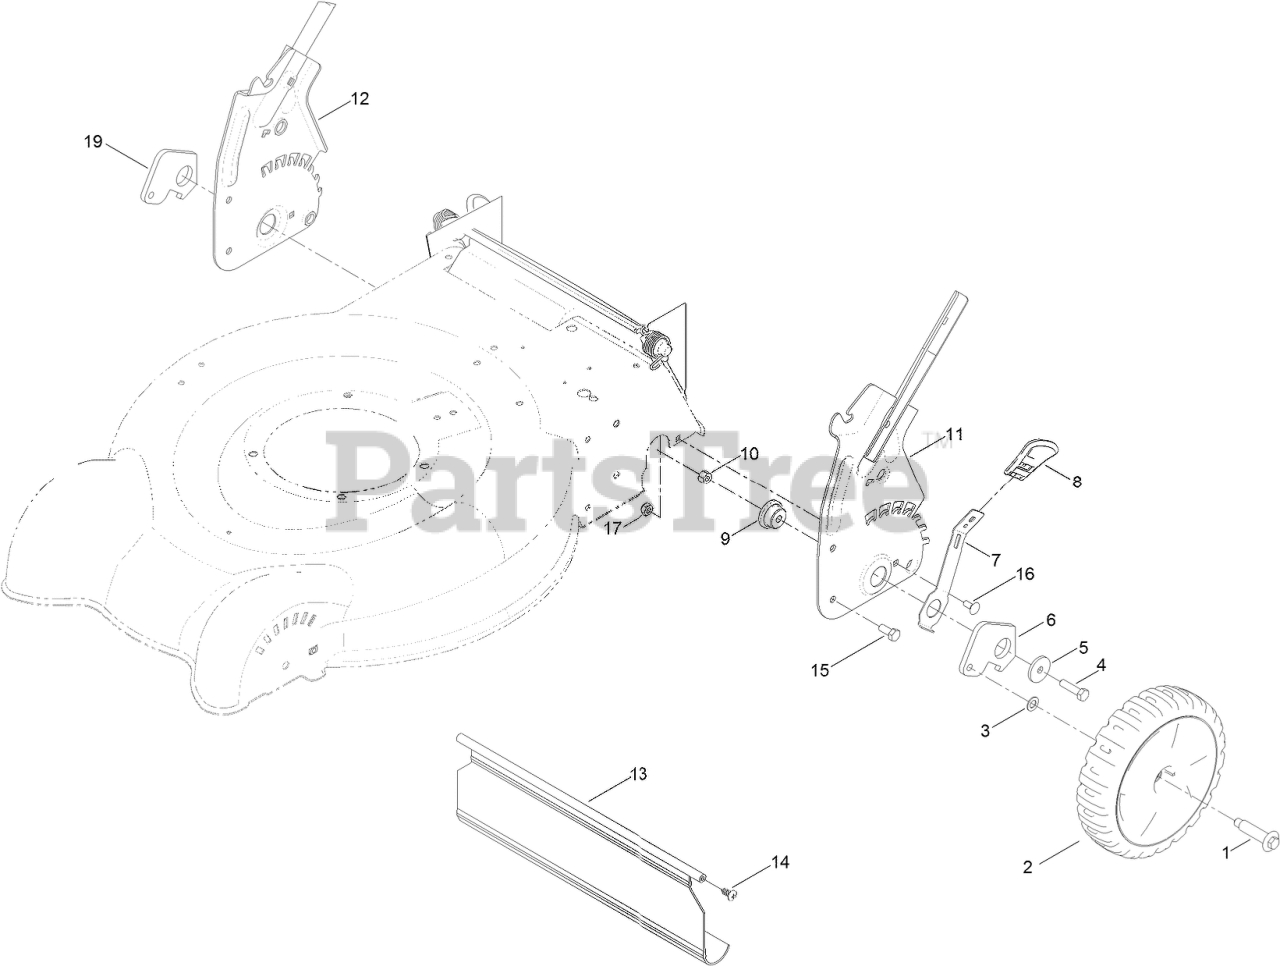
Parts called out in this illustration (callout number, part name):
1	BOLT-SHOULDER
2	8 INCH WHEEL AND TIRE ASM
3	WASHER
4	SCREW-HH
5	Washer-Flat
6	Arm-Pivot, Rear (LH)
7	Arm-Spring
8	KNOB-HOC
9	Bushing-Mount, HOC
10	NUT-LOCK, NI
13	SHIELD-TRAILING
14	SCREW-PTH
15	SCREW-HH
16	SCREW-CARR
17	NUT-LOCK, NI
19	ARM-PIVOT, REAR (RH)
